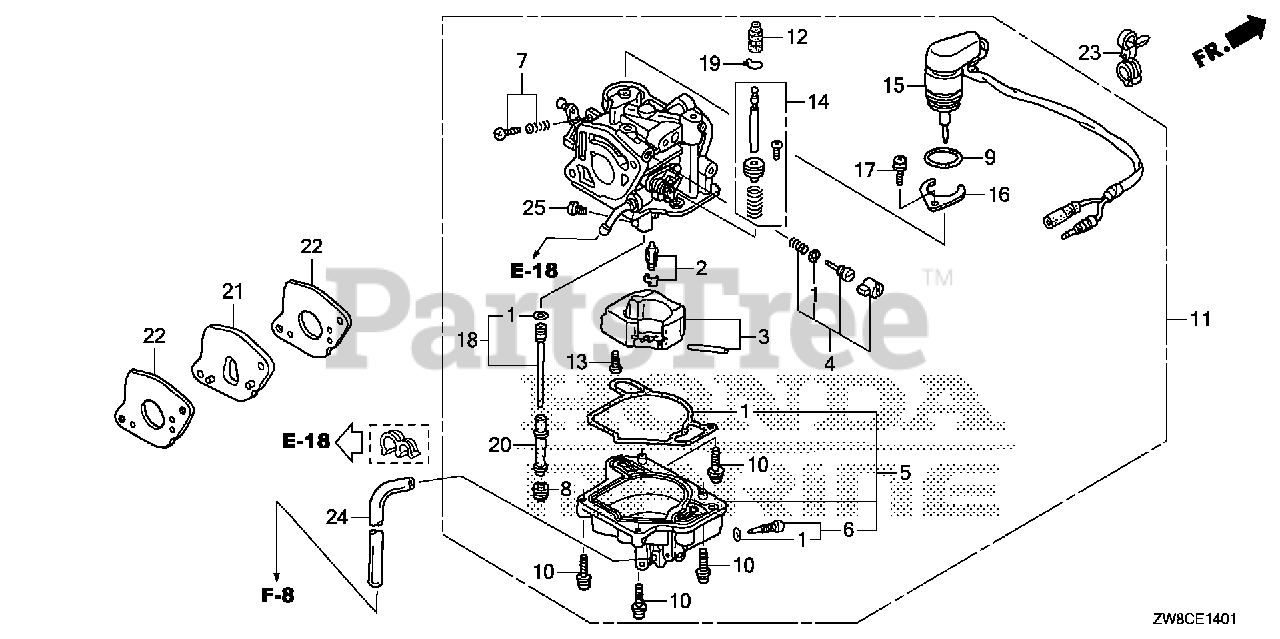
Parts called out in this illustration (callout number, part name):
1	GASKET SET
2	VALVE SET, FLOAT
5	CHAMBER SET, FLOAT
6	SCREW SET, DRAIN (CARBURETOR NO.)
7	SCREW SET
8	SCREW, PLUG
9	O-RING, BYSTARTER
10	SCREW-WASHER
11	CARBURETOR ASSY. (BJ05B D)
13	SCREW, PAN
14	PLUNGER SET, ACCELERATOR PUMP
15	BYSTARTER ASSY., AUTO
16	PLATE, SETTING
17	SCREW-WASHER
18	JET SET (#45)
19	CLIP, TUBE
20	NOZZLE, MAIN
21	INSULATOR, CARBURETOR
22	GASKET, CARBURETOR
23	CLIP, TUBE (135MM) (BLACK)
24	BULK HOSE, VINYL (4X7X8000) (95003-07(95003-07001-60M) (CARBURETOR NO.)
25	JET, MAIN (#98)
25	JET, MAIN (#102)
25	JET, MAIN (#105)
25	JET, MAIN (#108)
